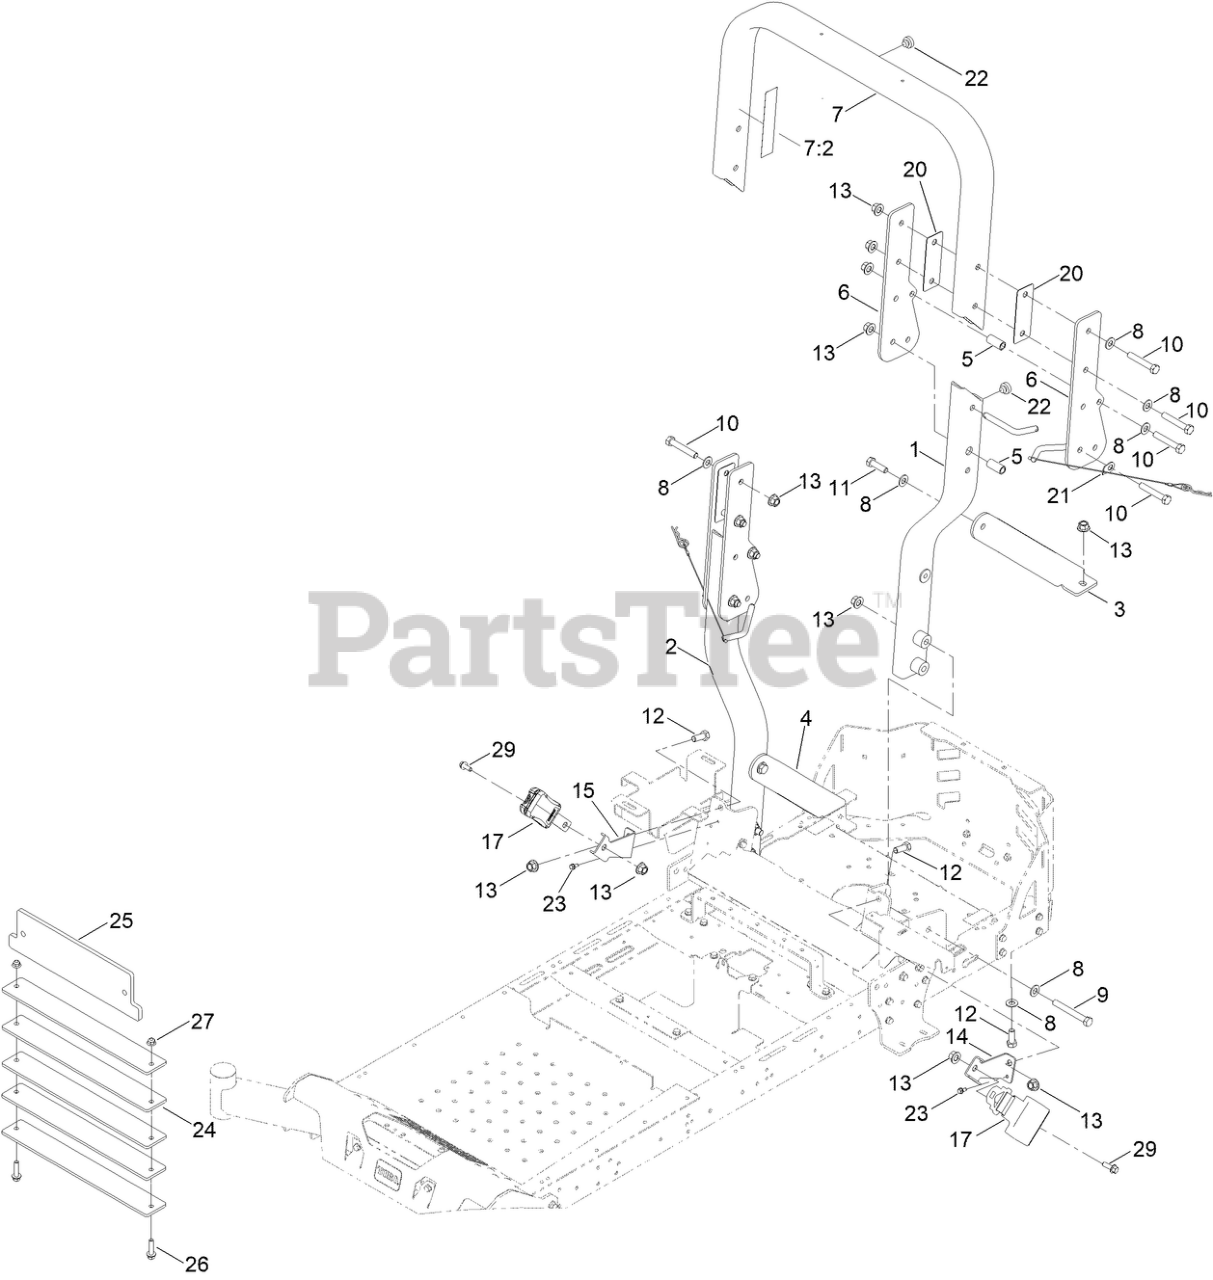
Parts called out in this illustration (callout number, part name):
1	TUBE-ROPS, LOWER (LH)
2	TUBE-ROPS, LOWER (RH)
3	BRACKET-SUPPORT (LH)
4	BRACKET-SUPPORT (RH)
5	SPACER
6	PLATE-SIDE
7	UPPER HOOP ASSEMBLY
7:2	DECAL-WARNING
8	WASHER-FLAT
9	SCREW-HH
10	SCREW-HH
11	SCREW-HH
12	SCREW-HH
13	NUT-HF
14	BRACKET-BELT, SEAT
15	BRACKET-BELT, SEAT
17	SEAT BELT KIT
20	SPACER-ROPS
21	PIN-ROPS
22	BUMPER-RUBBER
23	SCREW-HWH
24	WEIGHT-FRONT
26	SCREW-CARR
27	NUT-HF, NI
29	SCREW-HHF
